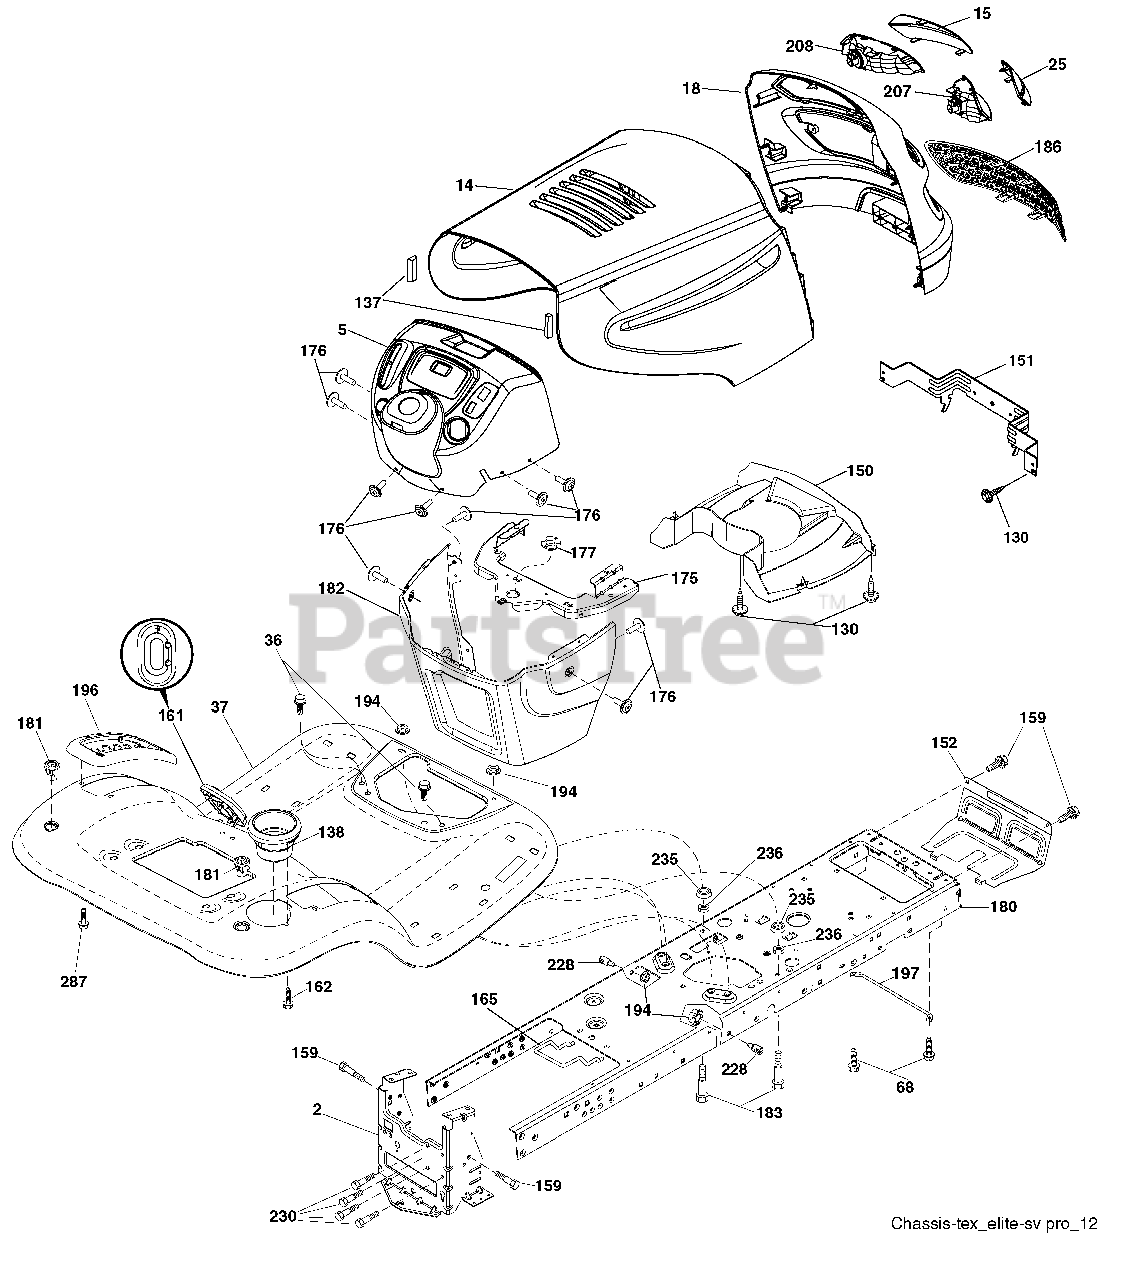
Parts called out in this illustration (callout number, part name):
2	Drawbar
5	Dash
14	Hood
15	Lens Grille LH
18	Grille
25	Lens Grille RH
36	Screw 5/16-18 x 3/4
37	Fender
68	Screw THDROL 5/16-18 x 1/2
130	Screw #10 x 0.750 BOS Thread
137	Bumper Hood
138	Cupholder
150	Duct Heat Hood
151	Bracket Pivot
152	Shield Browning/Debris
159	Screw Hexwsh Thdrol 3/8-16 x 3/4
161	Window Fuel
162	Screw Hex Wsh Hi-Lo 1/4 x 1/2 unc
165	Bracket Support Tank
175	Crossmember
176	Screw 10-24 x 5/8 Wshd Qdrx
177	Bushing Steering
181	Bushing Mtg. Fender Crgo.
182	Dash Lower
183	Bolt Fin Hex 5/16-18 x 1-1/4
194	Nut Lock Hex Flange 5/16-18
196	Console Asm. Deck Lift
197	Rod Pivot Chassis
207	Bezel RH
208	Bezel LH
228	Stud Fastener
230	Bolt Shoulder 5/16-18
235	Spacer Fender
236	Nut Center lock 5/16-18 unc
287	Screw Hex Washead 1/4-20 x 3/8
